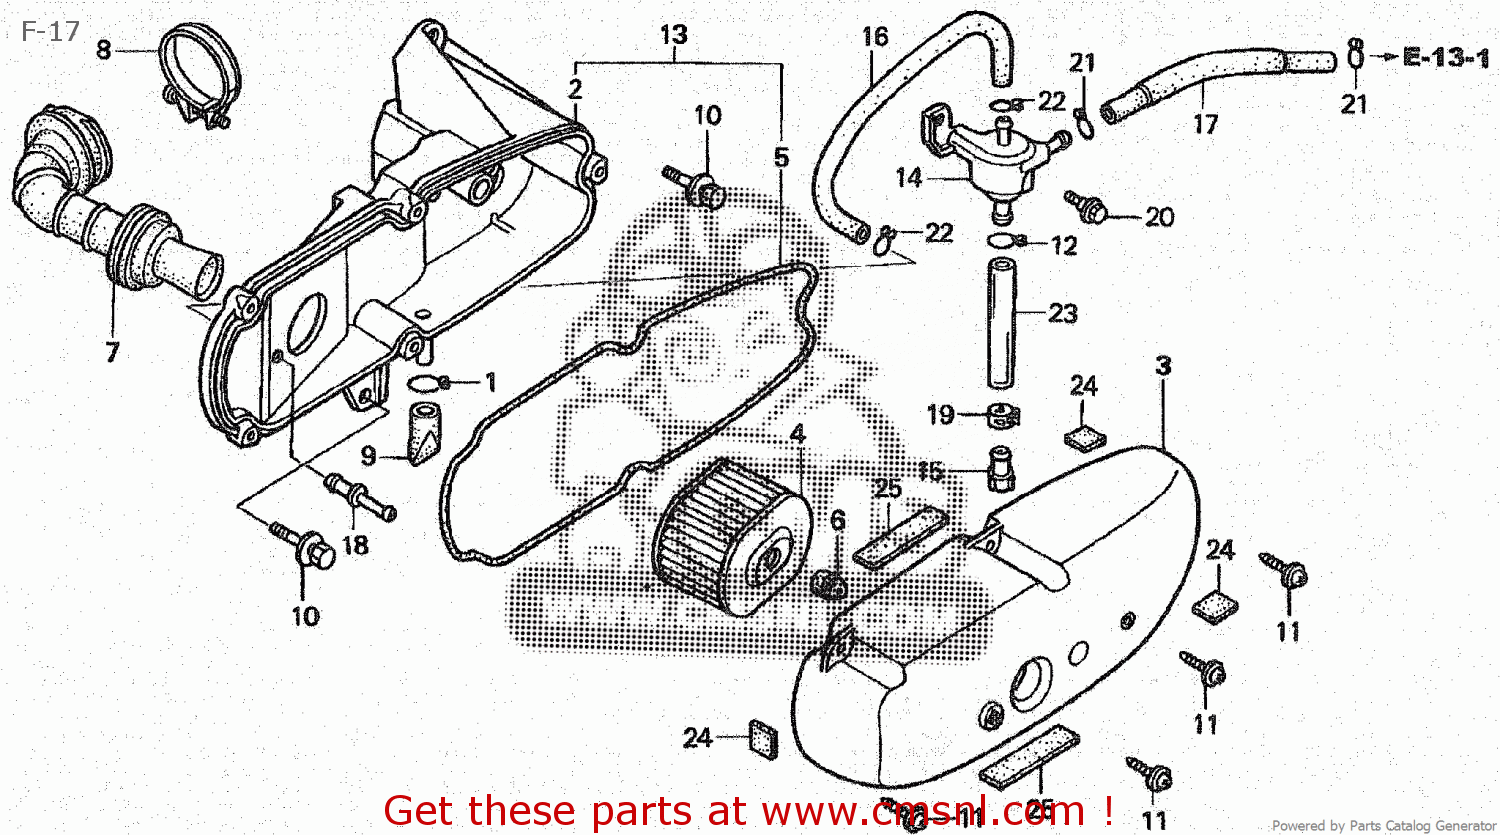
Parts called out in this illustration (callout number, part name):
1	CLIP,BRTHR TUBE
3	COVER,AIR/C (JDM)
4	ELEMENT COMP,AIR/
5	SEAL,AIR/C COVER
6	RUB,AIR/C ELEMENT
7	TUBE,AIR/C CONNEC
8	BAND,AIR CLEANER
9	TUBE,DRAIN
10	BOLT-WASHER,6X16
11	SCREW,TAP,5X16
12	CLIP,OIL DRAIN TU
13	CASE SUB ASSY,AIR (JDM)
14	TANK,BRTHR SERARA (JDM)
15	PLUG,BRTHR,TUBE
16	TUBE,BRTHR A (JDM)
17	TUBE,BRTHR B (JDM)
18	JOINT,B/B
19	CLAMPER,MASTER CY
20	BOLT,FLANGE,5X9
22	CLIP C11,TUBE
23	V,TUBE 11X15X80 (JDM)
24	CUSHION C,BATTERY
25	CUSHION,SEAT
